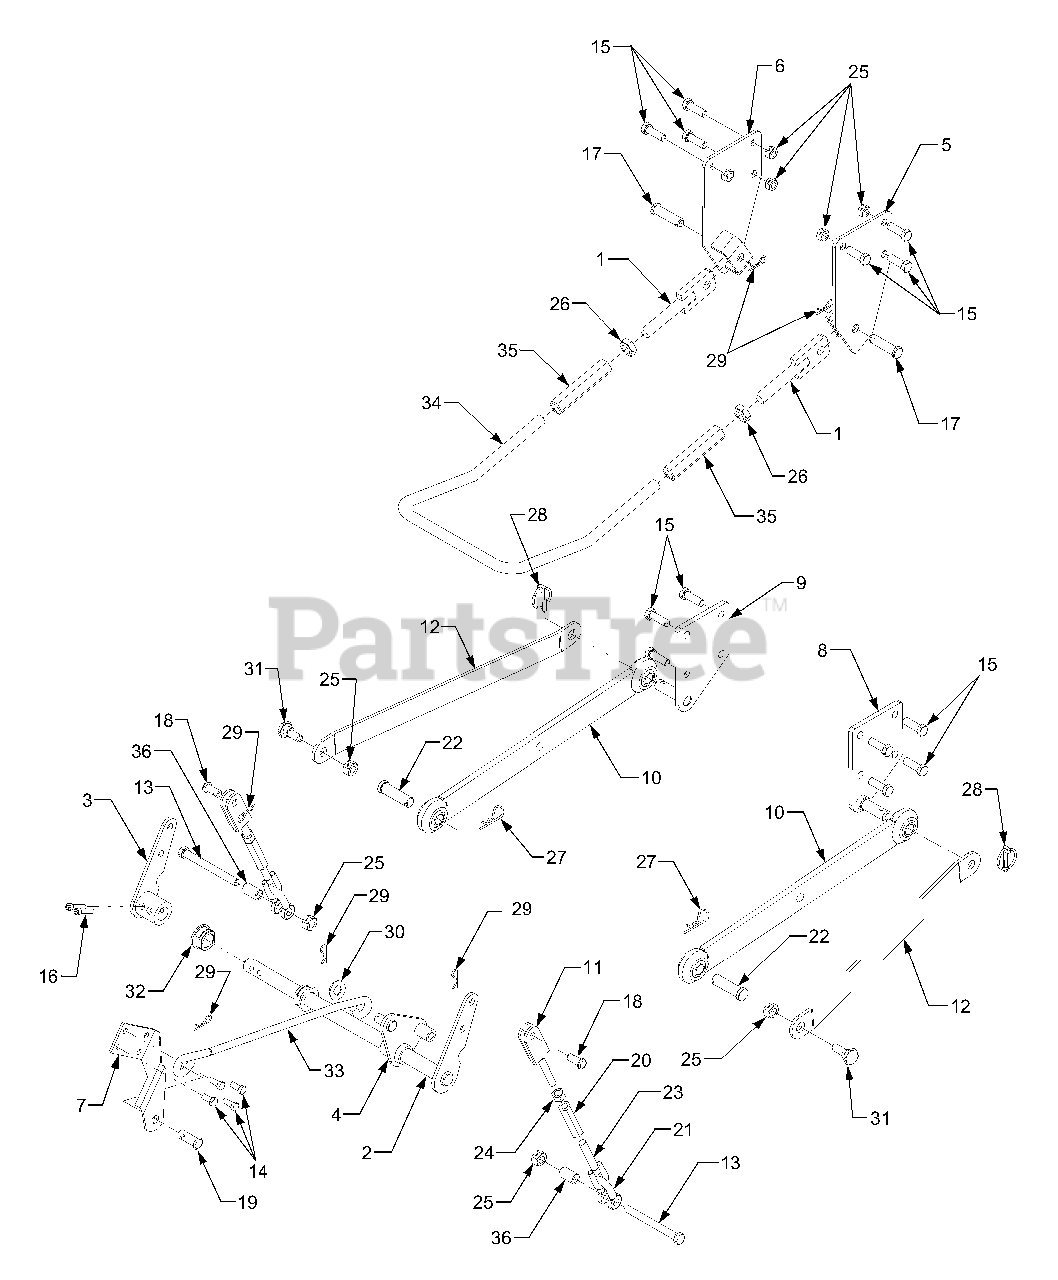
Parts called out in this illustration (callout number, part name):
1	Rod End, Deck Hanger
2	Shaft, Lift
3	Bracket, Lift
4	Crank, Deck Lift
5	Hanger, Front RH
6	Hanger, Front LH
7	Lever, Deck Lift
10	Arm, Deck Lift
12	Arm, Fixed Lift
13	Screw, Hex Cap, 1/2-13 x 5.0 GR5
14	Screw, Hex Cap, 3/8-16 x .88 GR5
15	Screw, Hex Cap, 1/2-13 x 1.50 GR5
16	Screw, Socket Hd. 5/16-18 x 1.50
17	Pin, Clevis, .625 x 2.4
18	Pin, Clevis, .5 x 1.18
19	Pin, Clevis
20	Shaft, Hex Check Chain
21	Clevis, Check Chain
22	Pin, Clevis, 3/4 x 2.50
23	Clevis, Chain
24	Nut, Hex, 1/2-13 GR5
25	Nut, Hex Lock, 1/2-23
26	Nut, Hex Jam, 3/4-10 GR5
27	Pin, Internal Cotter
28	Pin, Klik
29	Pin, Internal Cotter
30	Washer, Flat, .531 x .1.25
31	Screw, Shoulder, .625 x .36: 1/2-13
32	Bearing, Flange w/Flats
33	Rod, Crank Lift
34	Rod, Deck Hanger
35	Turnbuckle, Hanger Rod
36	Spacer, .50 x .75 x 1.25
